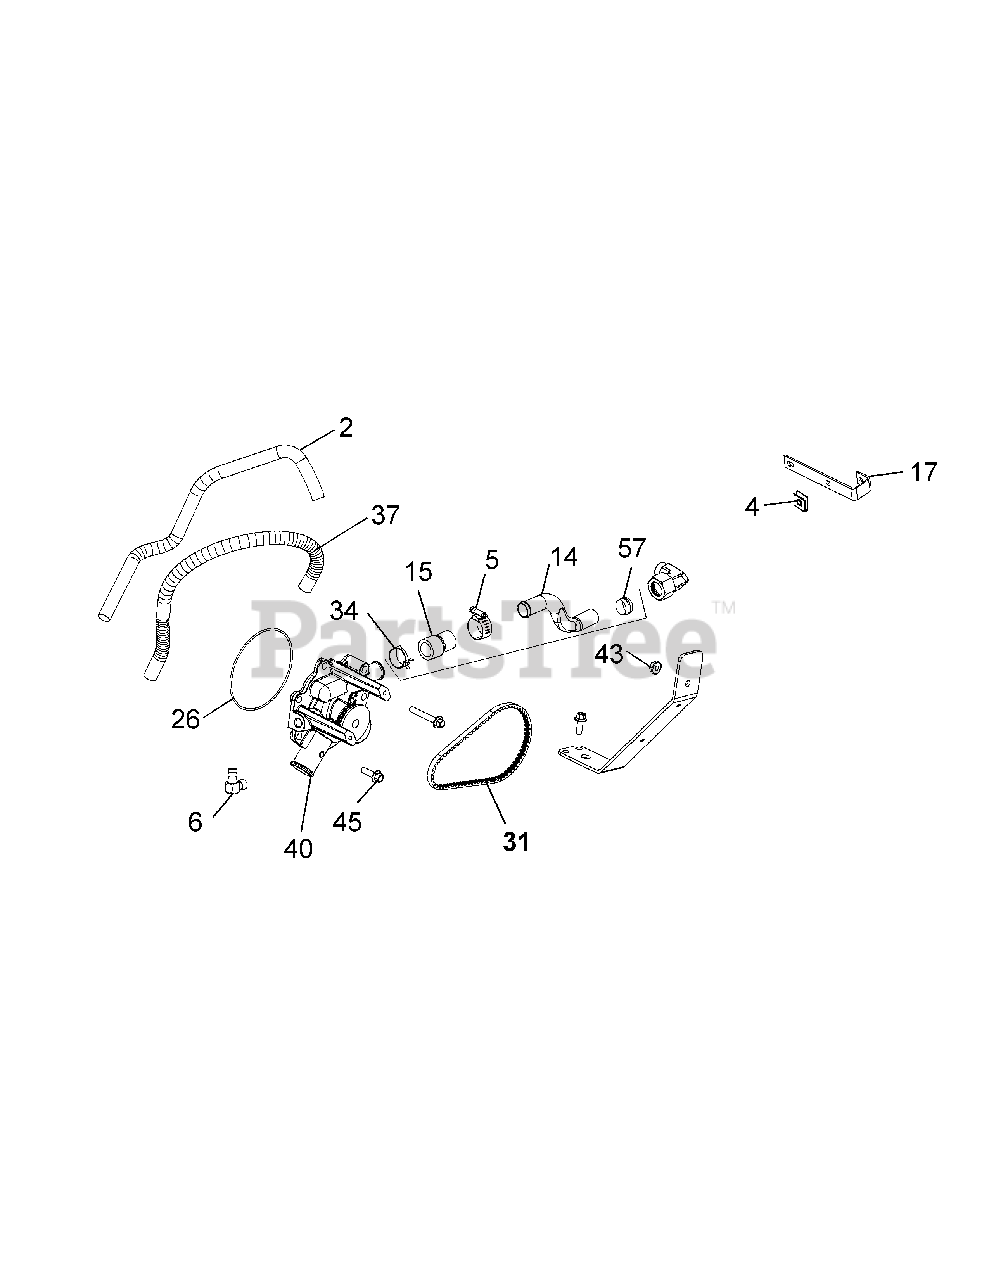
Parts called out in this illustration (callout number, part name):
2	Sleeve, Insulating 14"
4	Clip, Baffle Mounting
14	Tube, Crossover
15	Tube, Crossover
17	Bracket, Ignition Coil (EFI)
31	Belt, Water Pump
37	Hose, By-Pass (12.00")
40	Pump Assy, Water
43	Screw, Flg M6x1.0x40
45	Screw, Flg M6x1.0x20
